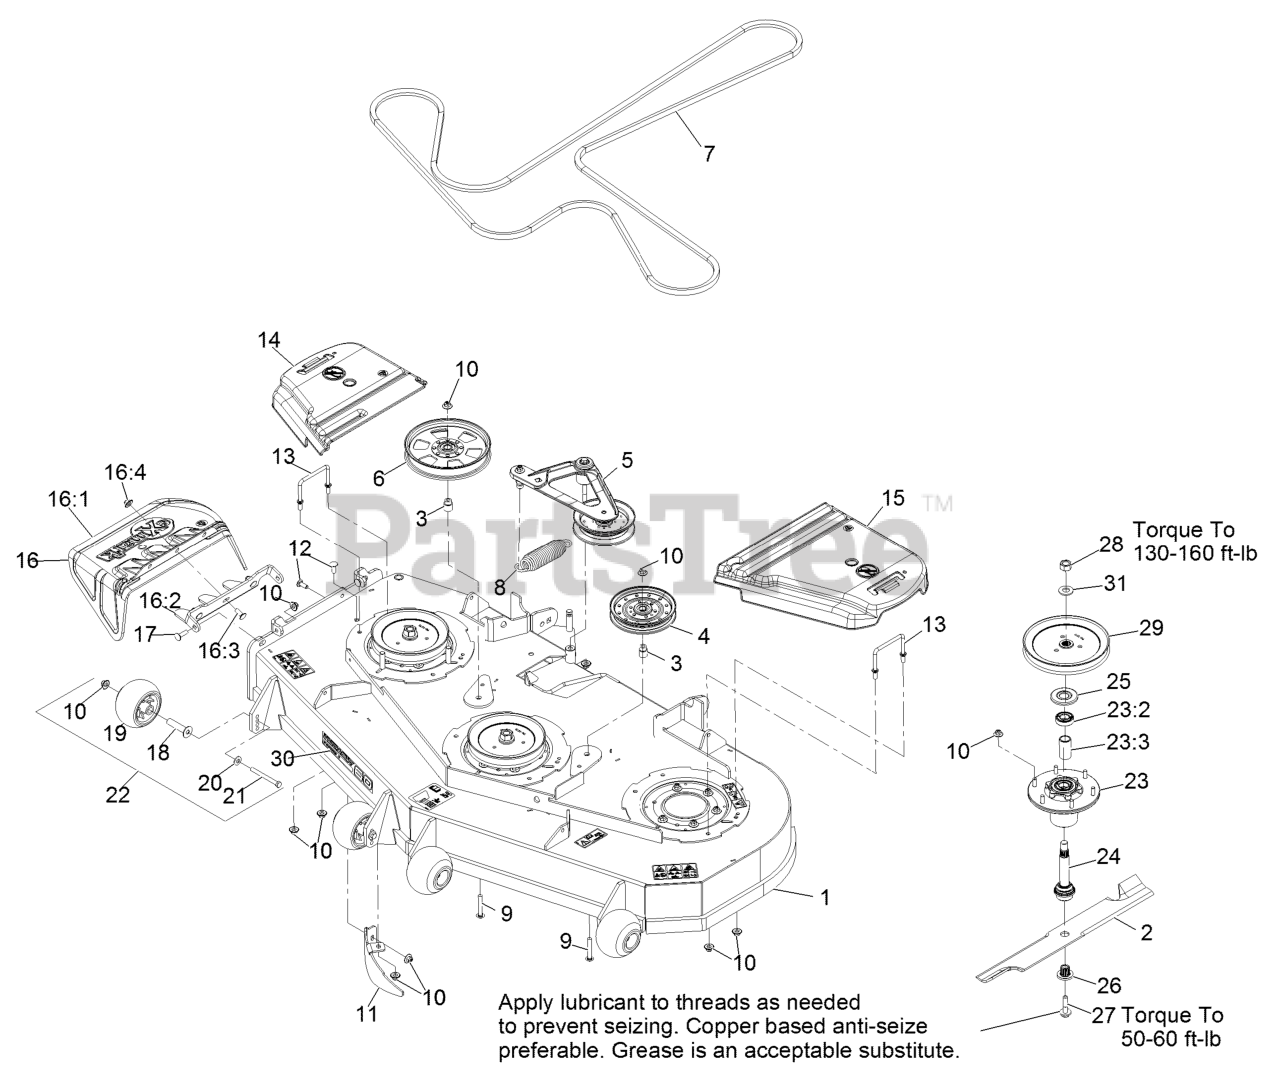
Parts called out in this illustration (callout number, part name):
1	DECK ASM,W/DECALS 60
2	Blade-Extreme 2, 20.50"
3	BUSHING-IDLER
5	DECK IDLER ASM
6	PULLEY-IDLER, FLAT
7	BELT,V-5V-198.75
8	SPRING-EXTENSION
9	SCREW-CARR
10	Nut-Nyloc 3/8-16 Flg
11	DOGLEG - LZ60
12	SCREW-CARR
13	WIREFORM-COVER
14	COVER-BELT, RH
15	COVER-BELT, LH
16	ASM,DISCHARGE CHUTE
16:1	CHUTE,DISCHARGE
16:2	BRACKET,DISCHARGE CHUTE
16:3	SCREW-CARR
16:4	Nut-Nyloc 3/8-16 Flg
17	Bolt-Carriage 3/8-16 X 1 1/4
18	AXLE, ROLLER
19	ROLLER-SCALP, ANTI
20	WASHER-BELLEVILLE
21	SCREW-HH 3/8-16 X 3 3/4 GR 8
22	KIT, ANTI-SCALP ROLLER
23	ASM-CUTTER HSG WITH BEARINGS
23:2	BEARING-BALL
23:3	SPACER-BEARING
24	ASM-SPINDLE AND SEAL
25	GUARD,BEARING TOP .989
26	BUSHING,SPLINED
27	SCREW,SEMS 1/2-20 X 2.19
28	NUT-HEX
29	SHEAVE,BLADE DRIVE 7.25
30	DECAL, 604
